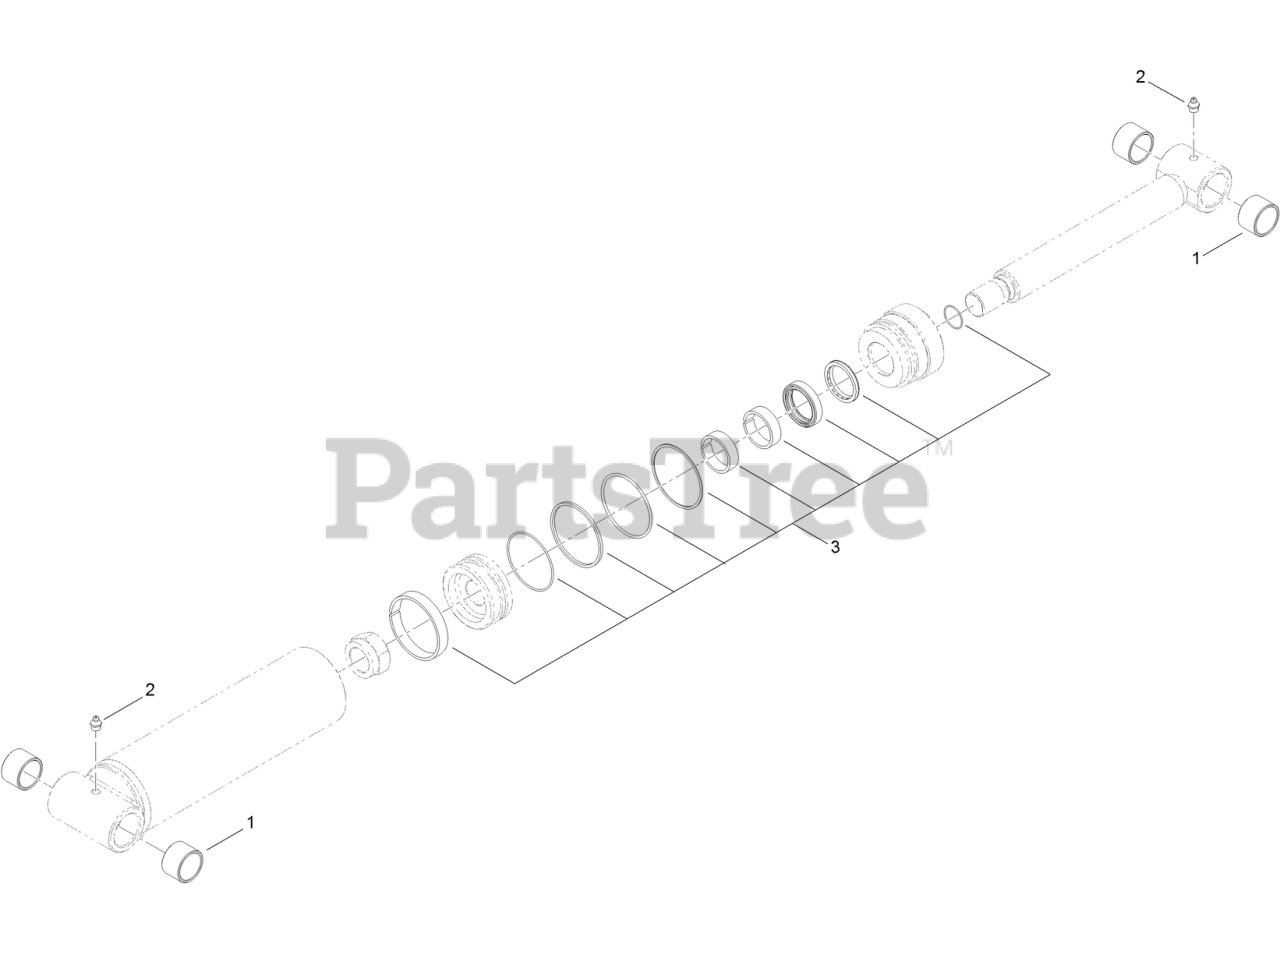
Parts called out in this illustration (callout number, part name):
1	BUSHING-ROD END, CYLINDER
2	FITTING-GREASE
3	SEAL KIT
